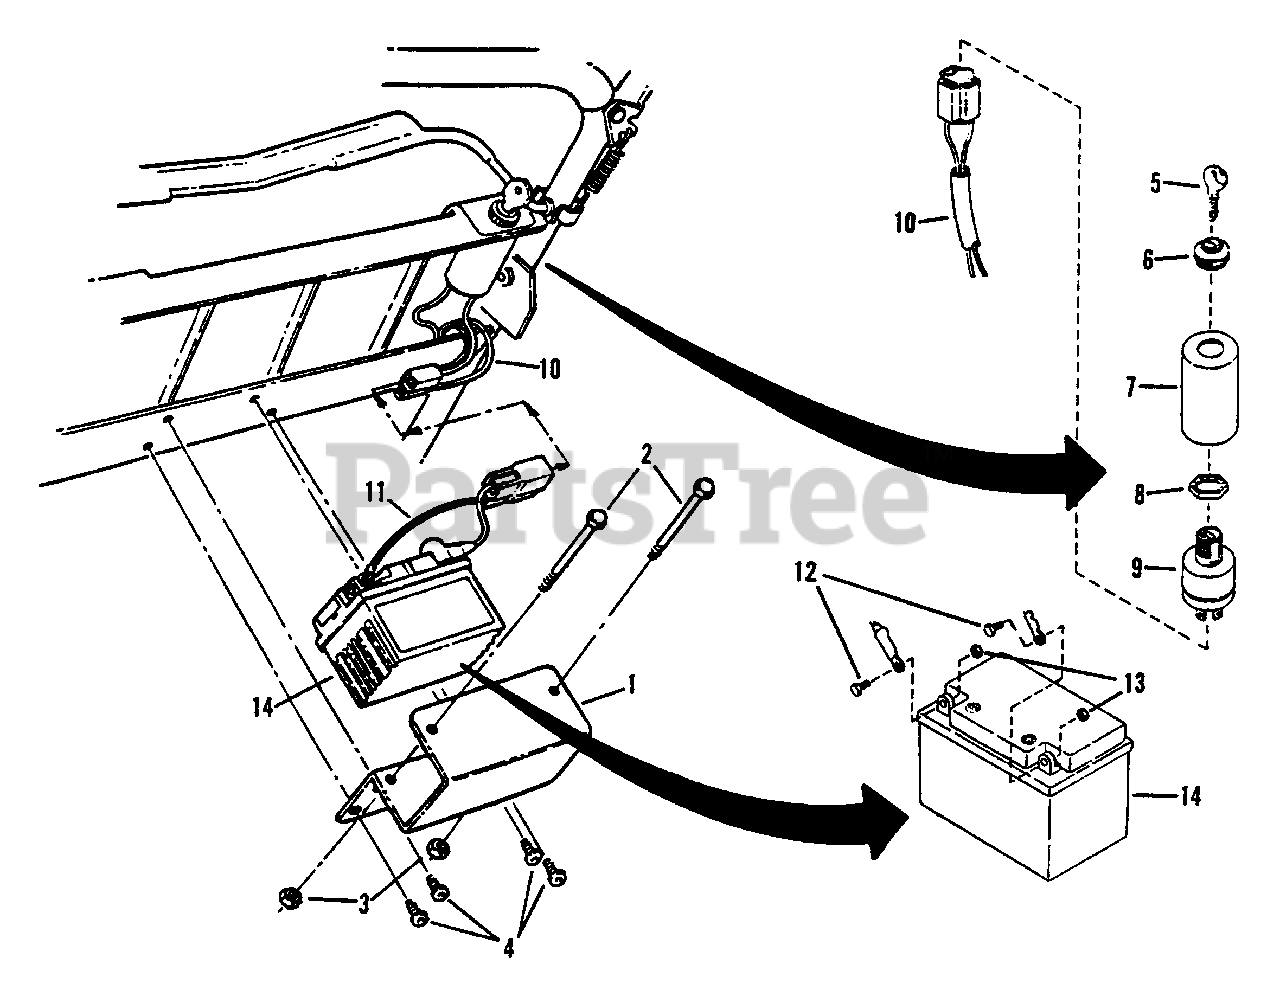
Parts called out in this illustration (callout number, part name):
1	BRACKET, Mounting
2	SCREW, 114-20 x 3-1/2" Hex Head Cap
3	NUT, 114-20 Hex Center Lock
4	SCREW, 1/4-20 x 518" Self-Tapping
5	KEY, Switch
6	ASSEMBLY, Seal A Face Nut
7	COVER, Switch
8	NUT, 3/4-20 Lock
9	SWITCH, Ignition
10	HARNESS, Wiring
11	HARNESS, Battery
12	SCREW, M70-8 x 10mm Hex Head Cap
13	NUT, M10-8 Hex
14	BATTERY 12V
